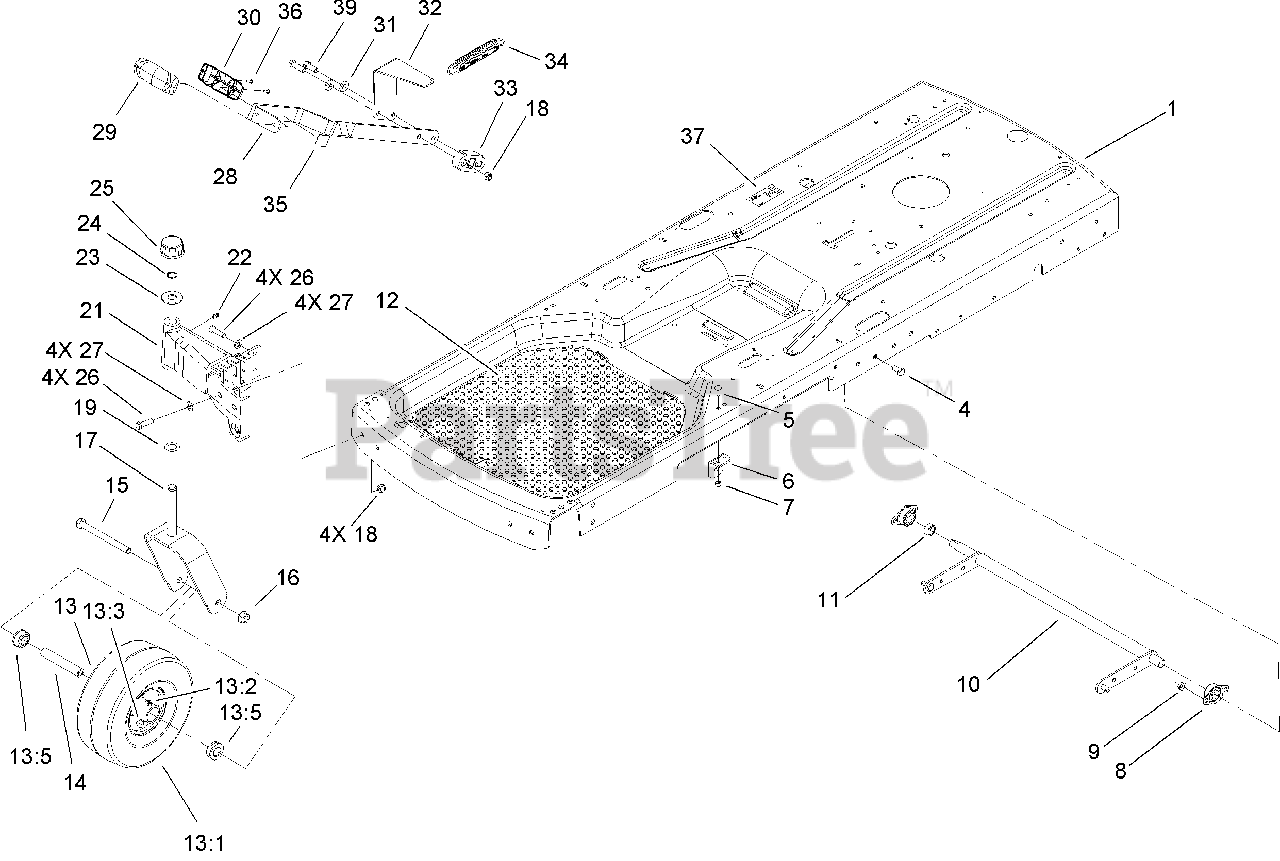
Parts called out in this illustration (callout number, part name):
4	SCREW-HH
5	SCREW-CARR
6	BRACKET-LIFT
7	NUT-LOCK, NI
8	BEARING-FLANGE, SIDE
9	NUT-HHF, WHIZ
10	LIFT ARM ASM
12	FOOTMAT-FRAME
13	CASTER WHEEL ASM
13:1	TIRE-SMOOTH
13:2	FITTING-GREASE
13:3	STEM-VALVE
13:5	BUSHING-FLANGE
14	SPANNER-WHEEL
15	SCREW-HH
17	CASTOR FORK ASM
18	NUT-LOCK, NI
19	WASHER-THRUST
22	FITTING-GREASE
24	RING-RETAINING, EXT
26	SCREW-HH
27	WASHER-FLAT
29	HANDLE-TOP
30	HANDLE-BOTTOM
31	WASHER-BELLEVILLE
32	MOUNT-SPRING, FRONT
33	BLOCK-LIFT
34	SPRING-EXTENSION
37	DECAL-TRANSPORT, CE
39	SCREW-HH
